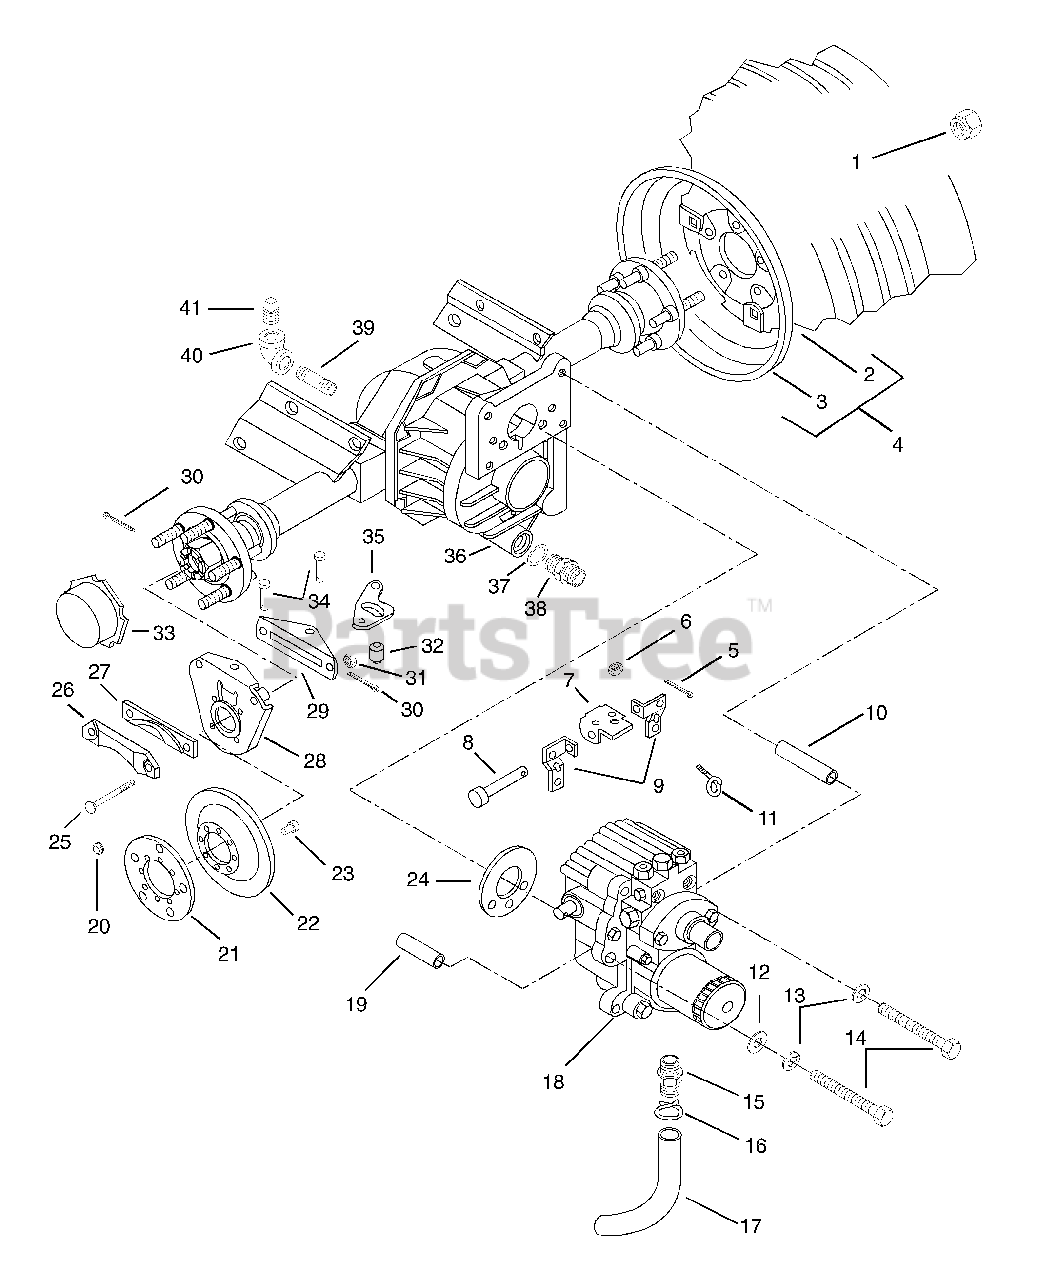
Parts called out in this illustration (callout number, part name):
1	NUT-LUG .437-20 YWZC
4	T/WHL ASSY 10.50X23
5	@PIN-CTR .09X.50 EXTPRSQCT YWZ
6	@NUT-SPNLK-FLG .25-20 YWZC
8	CLEVIS PIN
9	SUPPORT
10	SPACER .379X.625X3.480
11	CABLE SUPPORT
12	WSHR-FL-STL .390X.75X.125 YWZC
13	@WSHR-LK .38X.094 REG YWZC
14	@BLT-HEX .38-16X5.00 GR5 YWZC
15	FTG-ADPTR 88-14
16	HOSE CLAMP #15 .906/.968
17	HOSE .62X.91X8.00
18	TRANSMISSION ASS'Y
19	SPACER .379X.625X3.220
20	GROMMET
21	CARRIER
23	@SCR-TAP .25-20X.37 HWH YWZ TR
25	@BLT-RDHDSQNK .38-16X3.50 G5YZ
26	CALIPER PLATE
27	FRICTION PLATE
28	PLATE, CALIPER MOUNTING
29	PRESSURE PLATE
30	@PIN-CTR .09X.75 EXTPRSQCT YWZ
31	@NUT-LK-CTR .38-16 YWZC
33	REAR HUB CAP
34	PIN-CLEV .371X1.62 YWZC
35	BRAKE ARM
36	REAR AXLE & SUPPORTS
37	O-RING .924X1.156X.116
38	CONNECTOR
39	PIPE NIPPLE
40	ELBOW 1/2 X 90
41	PIPE PLUG
